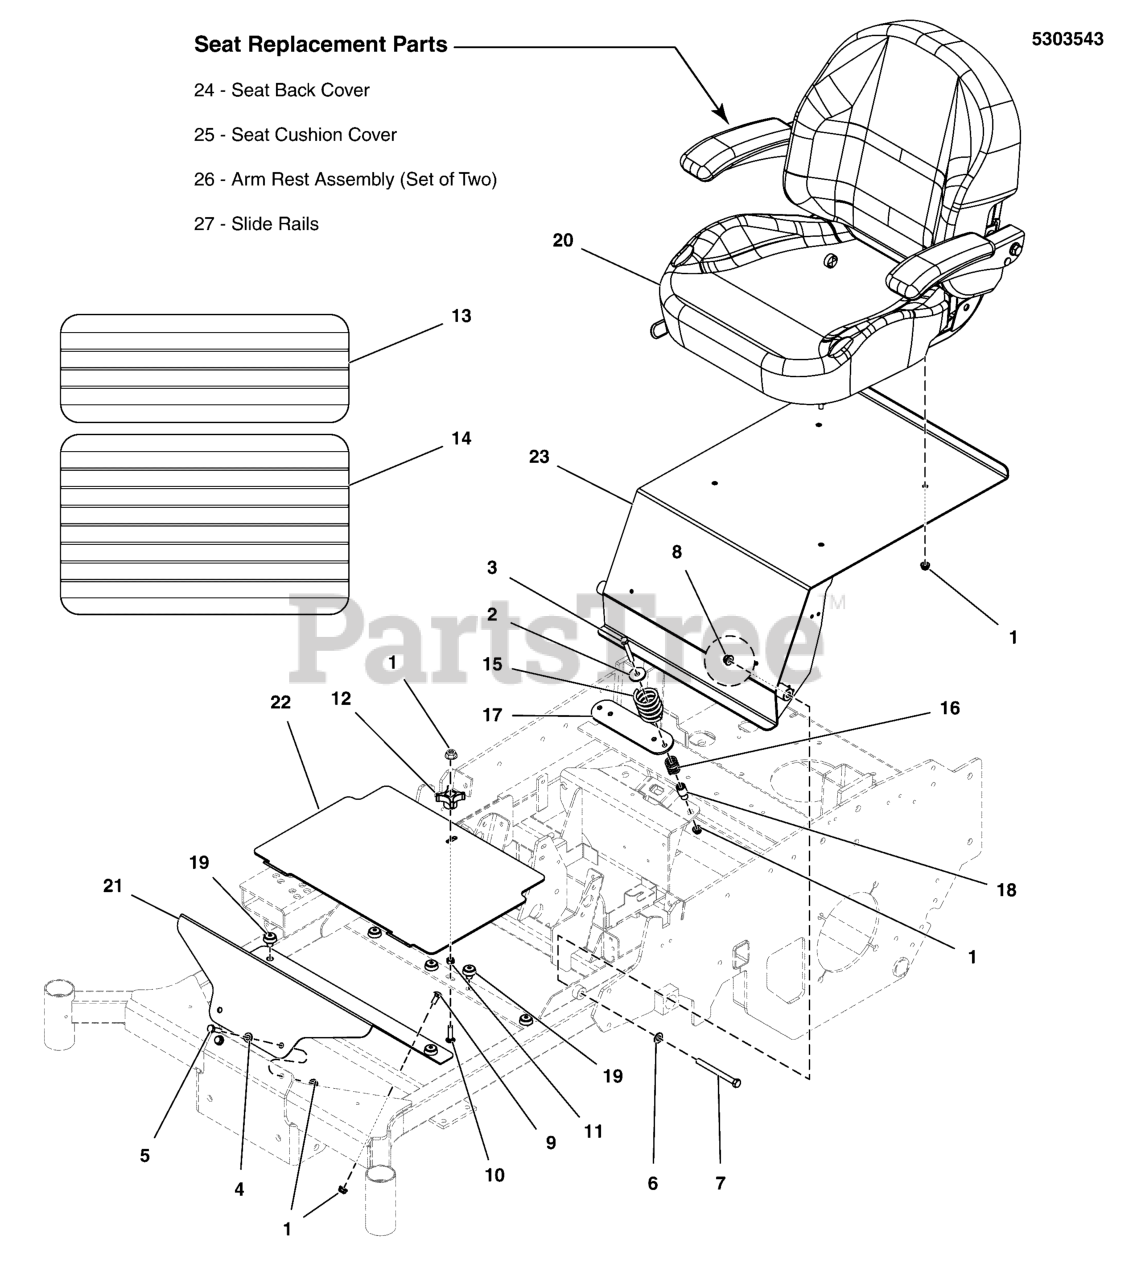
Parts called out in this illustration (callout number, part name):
1	NUT, 5/16-18 HEX NYLOCK FLANGE NUT
2	WASHER, .34 X 1.25 X 10 GA
3	BOLT, 5/16-18 X 2-1/4" GD5 YZ
4	WASHER, 5/16" SAE
5	BOLT, 5/16-18 X 1" GRD5 YZ
6	WASHER, 3/8 SAE
7	BOLT, 3/8-16 X 4" GD5 CZ
8	NUT, 3/8 - 16 HEX NYLOCK FLANGE
9	BOLT, 5/16-18 X 3/4, CARRIAGE, GD5, CZ
10	BOLT, 5/16-18 X 1-1/4, CARRIAGE, GD5, CZ
11	NUT, 5/16-1/8, HEX, CNTR LK, ZINC PHOS/OIL
12	KNOB-INT THR .312-18 4-ARM 2.12WD 1.06LG
13	SAFETY WALK, FLOOR REST, 16.00 X 6.00
14	SAFETY WALK, FLOOR PLATE, S50X, 10X17.13
15	SPRING, SEAT SUPPORT
16	SPRING-COMP, .720ID X 1.310LG X .118 WIRE
17	PLATE, SEAT SWITCH - RED
18	SPACER, .33 X .66 X 1.31 SHLDR, CZ
19	MNT, VBRTN, RBBR
20	SEAT - 2012
21	PLATE, FLOOR, NON REMOVABLE - RED
22	PLATE, FLOOR, REMOVABLE, S125XT - RED
23	ASSM, SEAT PLATE W/ DECALS, S150XT (5411151D)
23	ASSM, SEAT PLATE W/ DECALS, S150XT-DOM (5413405D)
24	SEAT BACK COVER, SEAT 2012
25	SEAT COVER
26	Arm Rest Asm. (set of 2)
27	SLIDE RAILS
